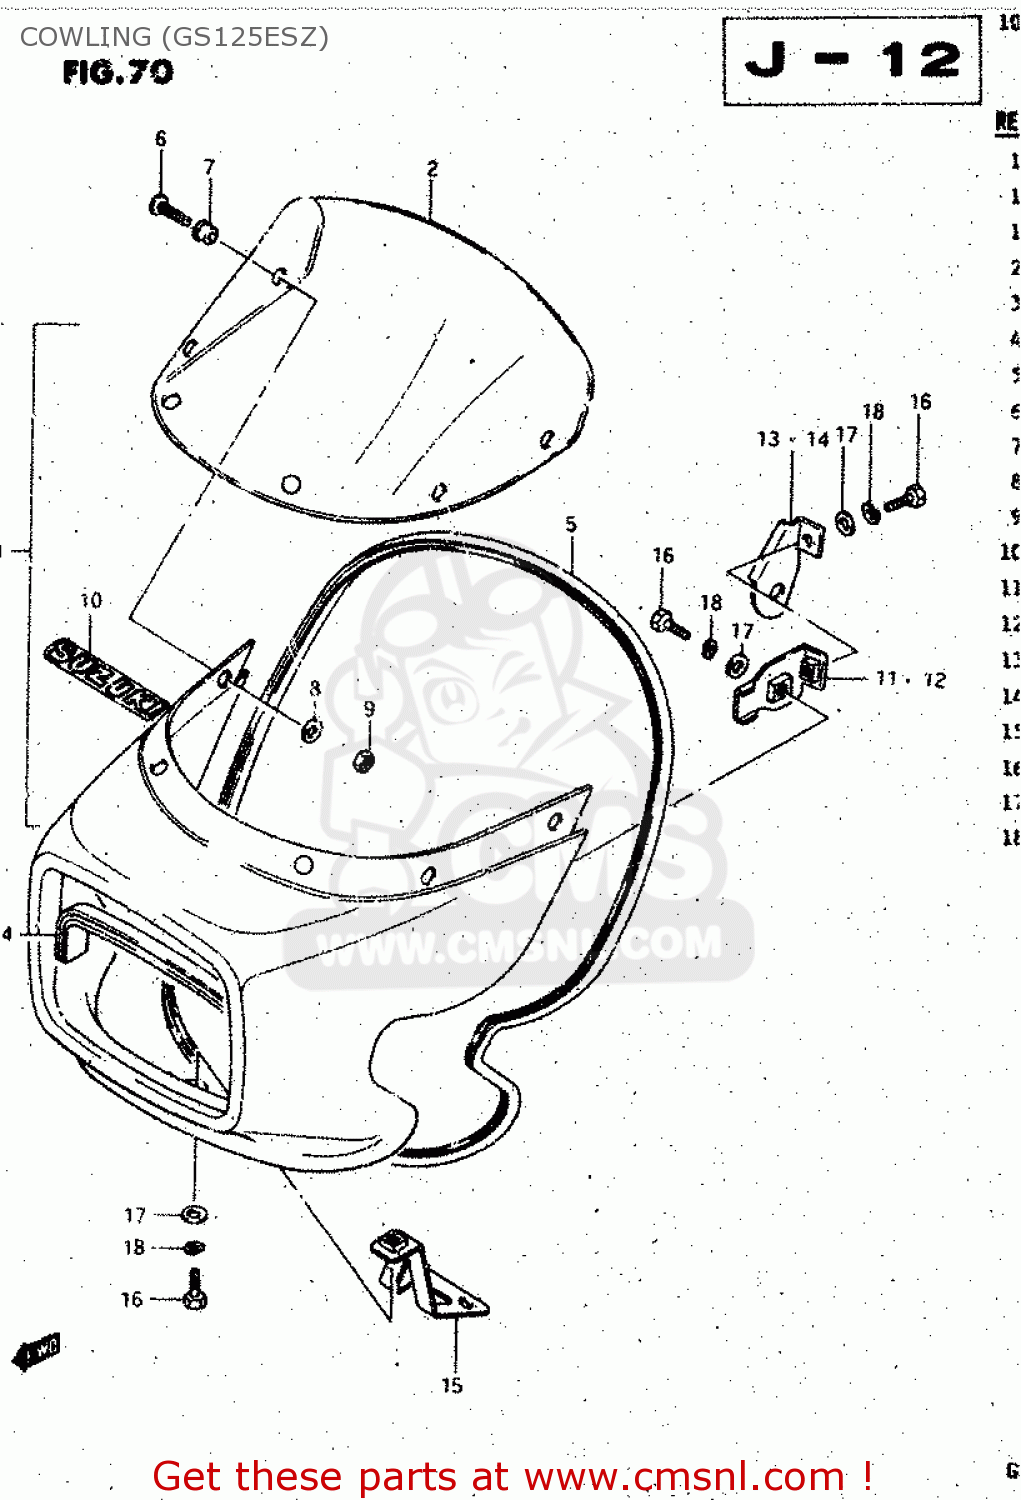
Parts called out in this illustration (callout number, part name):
1	COWLING ASSY (RED)
2	WINDOW,COWLING
3	MOLDING,HEADLAMP GRILL
4	MOLDING,HEADLAMP GRILL
5	MOULDING, WINDOW
6	SCREW, FRONT & REAR
7	CUSHION
8	WASHER,5MM
9	NUT ,5MM
10	EMBLEM,SEAT TAIL COVER
11	BRACE, RH (L:19)
12	BRACE,COWLING LH
13	BRACKET, FITTING RH (L:19)
14	BRACKET,L
15	BRACKET, LOWER
16	BOLT 6X16
17	WASHER (6.5X18X1.6)
18	WASHER,LOCK
